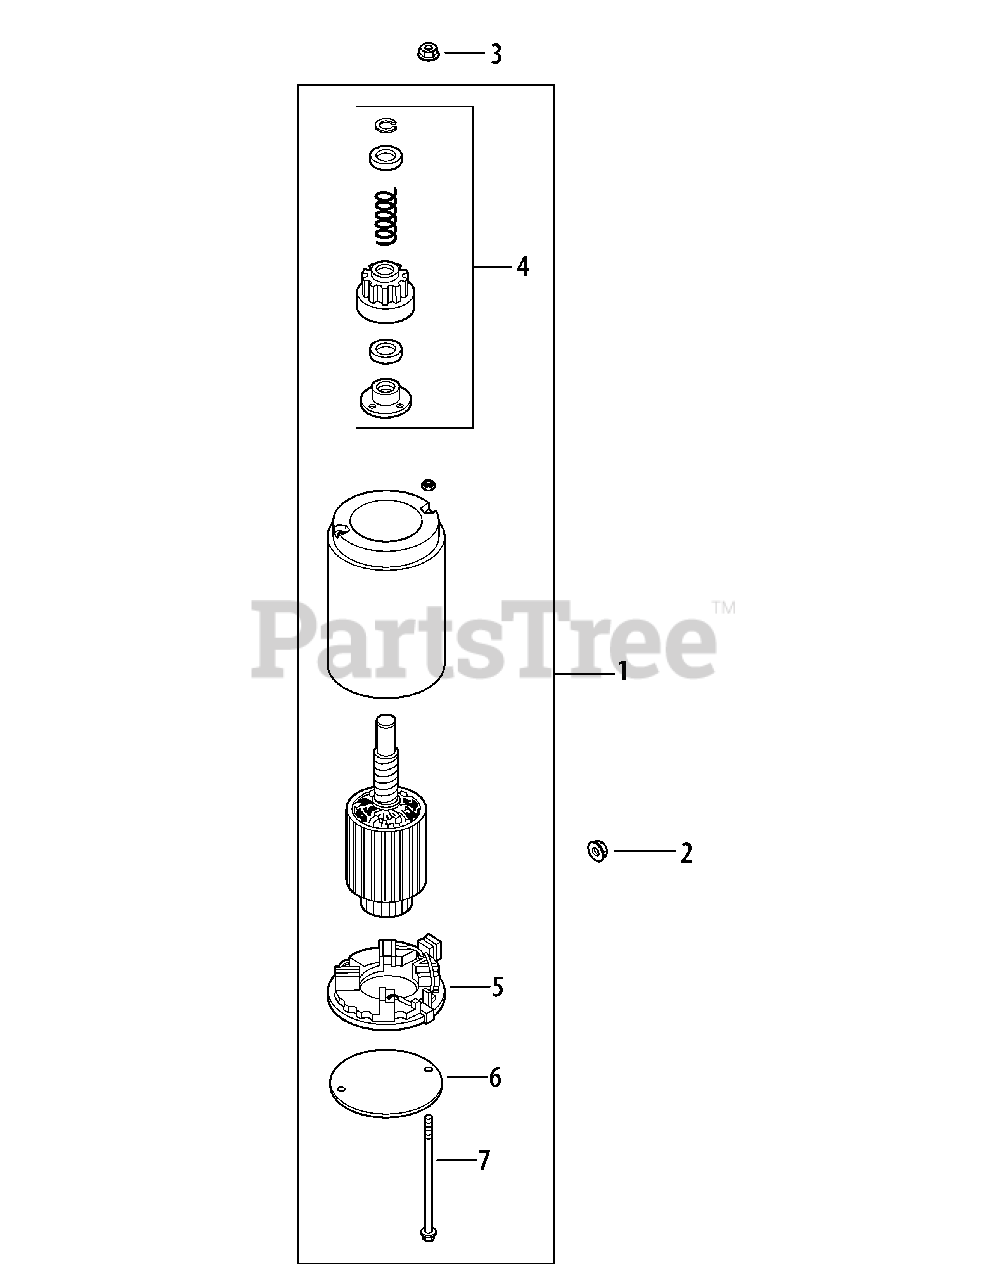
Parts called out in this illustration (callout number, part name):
1	Starter Assembly (Inc. 4-7)
3	Free Spinning Flg. Nut, #10-24
4	Drive Kit (J.E.)
6	Drive End Cap (J.E.)
